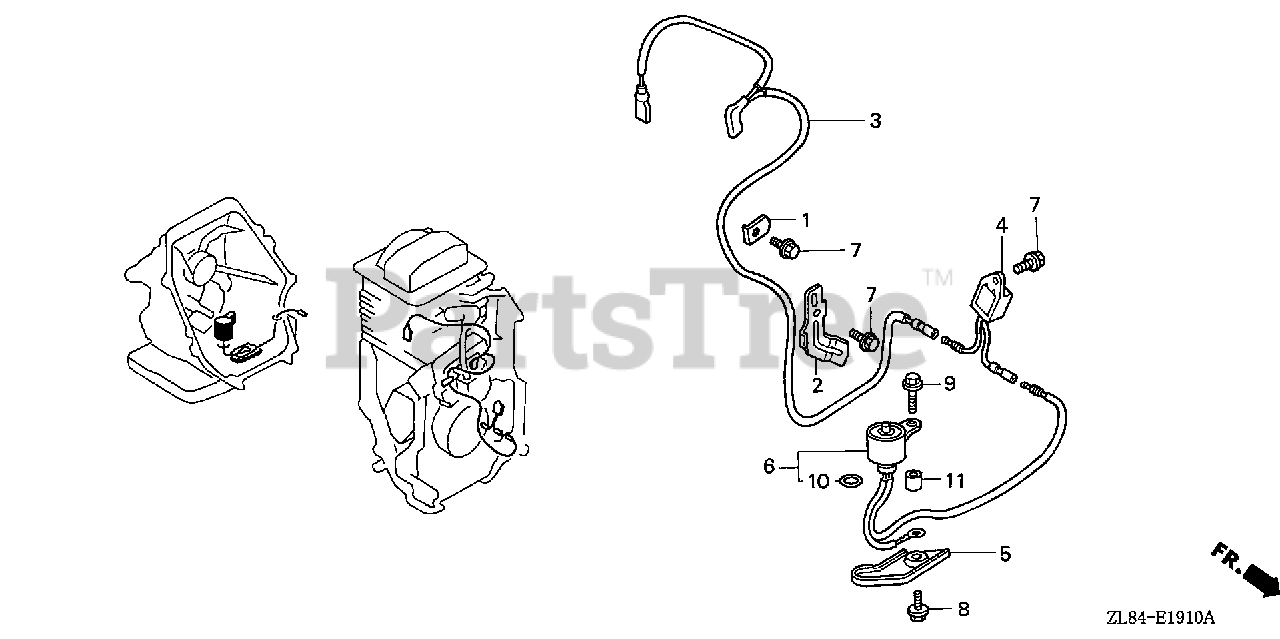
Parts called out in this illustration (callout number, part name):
1	CLAMP, STOP SWITCH WIRE
2	CLAMP, WIRE
3	WIRE, STOP SWITCH
4	ALERT UNIT, OIL
5	PROTECTOR, SWITCH
6	SWITCH, OIL LEVEL
7	BOLT, FLANGE (6X12) (CT200)
8	BOLT, FLANGE (6X14)
9	BOLT, FLANGE (6X28)
10	O-RING (11.8X2.4)
11	COLLAR (6.6X13.8X14.5)
